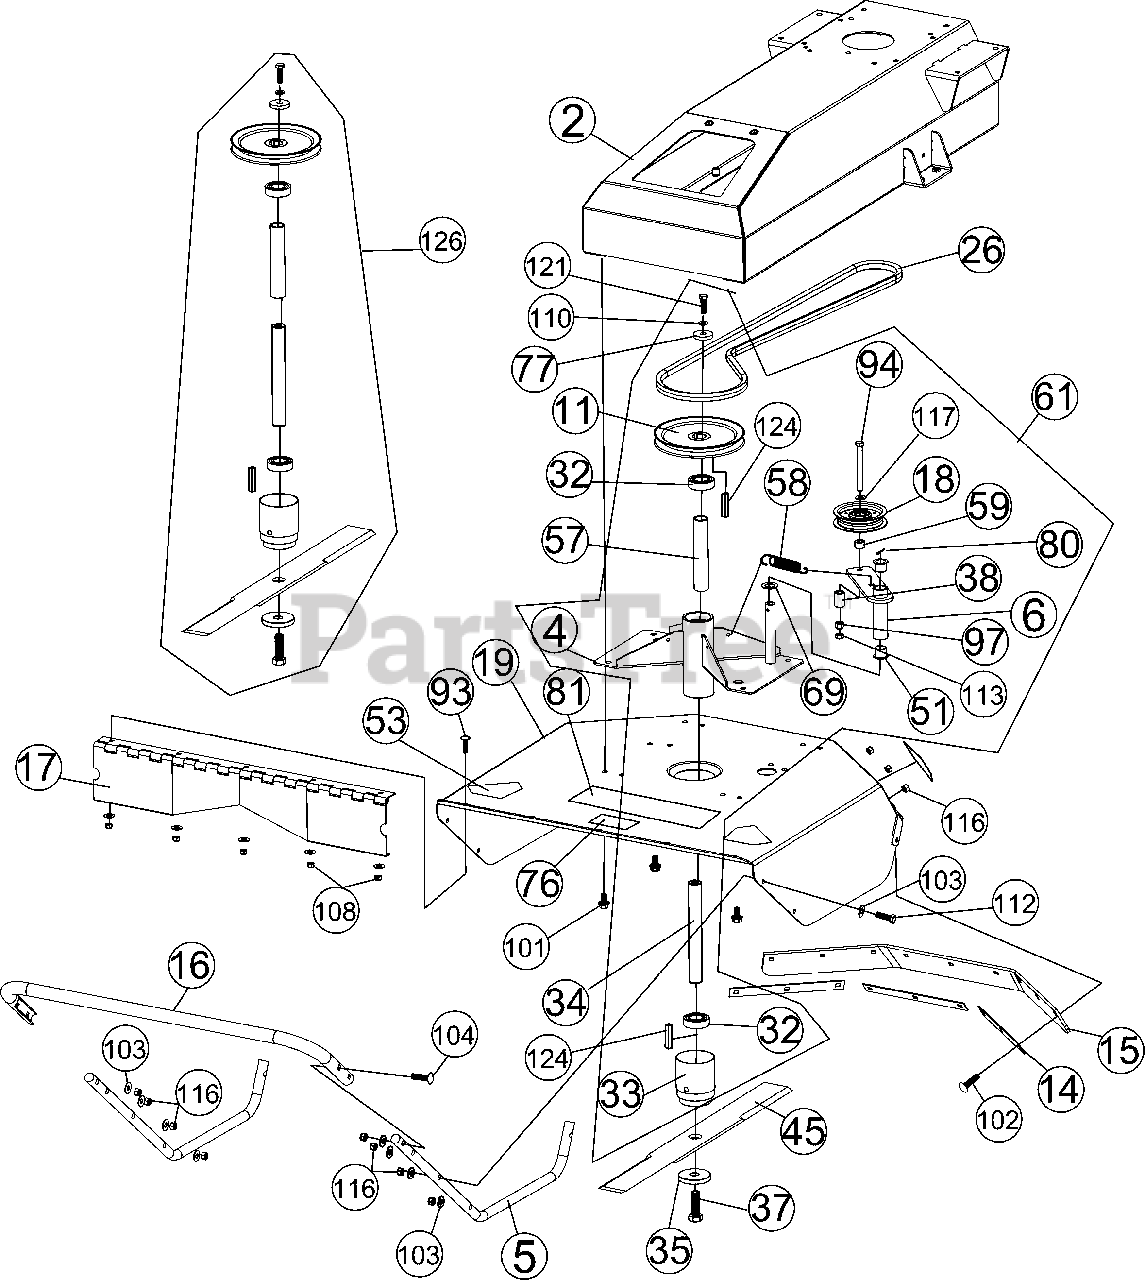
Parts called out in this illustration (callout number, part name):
2	BASE ENGINE BC26 FIXED WA W/LABELS
4	BRACKET DECK MOUNT WA BC
5	SKID BC26
6	ARM IDLER DECK WA BC
11	PULLEY 7" OD X 1.00" BORE
14	PLATE CLAMP SKIRTING BC26
15	DEFLECTOR RUBBER BC26
16	BAR GUARD BC26
17	HINGE DEFLECTOR BC26
18	PULLEY IDLER 4.00" OD X 3/8" BORE
19	DECK WA W/LABELS BC26
26	BELT 6972 POWERATED
32	BEARING 1.00" SEALED PRESS IN
33	ADAPTER BLADE WA BC26
34	SHAFT BLADE BC2600
35	WASHER BLADE BC26
37	SCREWCAP 9/16"-18 X 1 3/4" GR 8
38	BUSHING PIVOT LIFT
45	BLADE 26" FLAT BC26
51	BUSHING PIVOT FRAME AE
53	LABEL DANGER
57	SPACER SPINDLE BEARING BC2600
58	SPRING IDLER
59	TUBE PIVOT IDLER VQ
61	SPINDLE ASSY BC26 FIXED
69	WASHER .765" ID X 1.25" OD X .06"
76	LABEL DANGER FLYING DEBRIS
77	WASHER 1.5 OD X .453 ID X .25 THK
80	PIN COTTER 1/8" X 1"
81	LABEL OUTBACK BC26 MECH
93	BOLT CARRIAGE 1/4"-20 X 3/4" ZP
94	SCREWCAP 3/8"- 16 X 3 3/4" HCS ZP
97	NUT LOCK 3/8"-16 HEX
101	SER HEX WSHR FLNG SCR .375" - 16 X .75"
102	BOLT CARRIAGE 5/16"-18 X 1" ZP
103	WASHER 5/16" FLAT ZP
104	BOLT CARRIAGE 5/16"- 18 X 1 1/4" ZP
108	NUT LOCK 1/4"-20 HEX ZP
110	WASHER LOCK 3/8" S/T MED
112	SCREWCAP 5/16"-18 X 1 1/2" HCS ZP
113	NUT LOCK 3/8"- 16 LT WT TH ZP
116	NUT LOCK 5/16"-18 HEX ZP
117	WASHER 3/8" SAE
121	SCREWCAP 3/8"-16 1 1/4" HCS ZP
124	KEY 1/4" SQ X 3/4"
126	BLADE PULLEY AND ADAPTER KIT SERVICE
